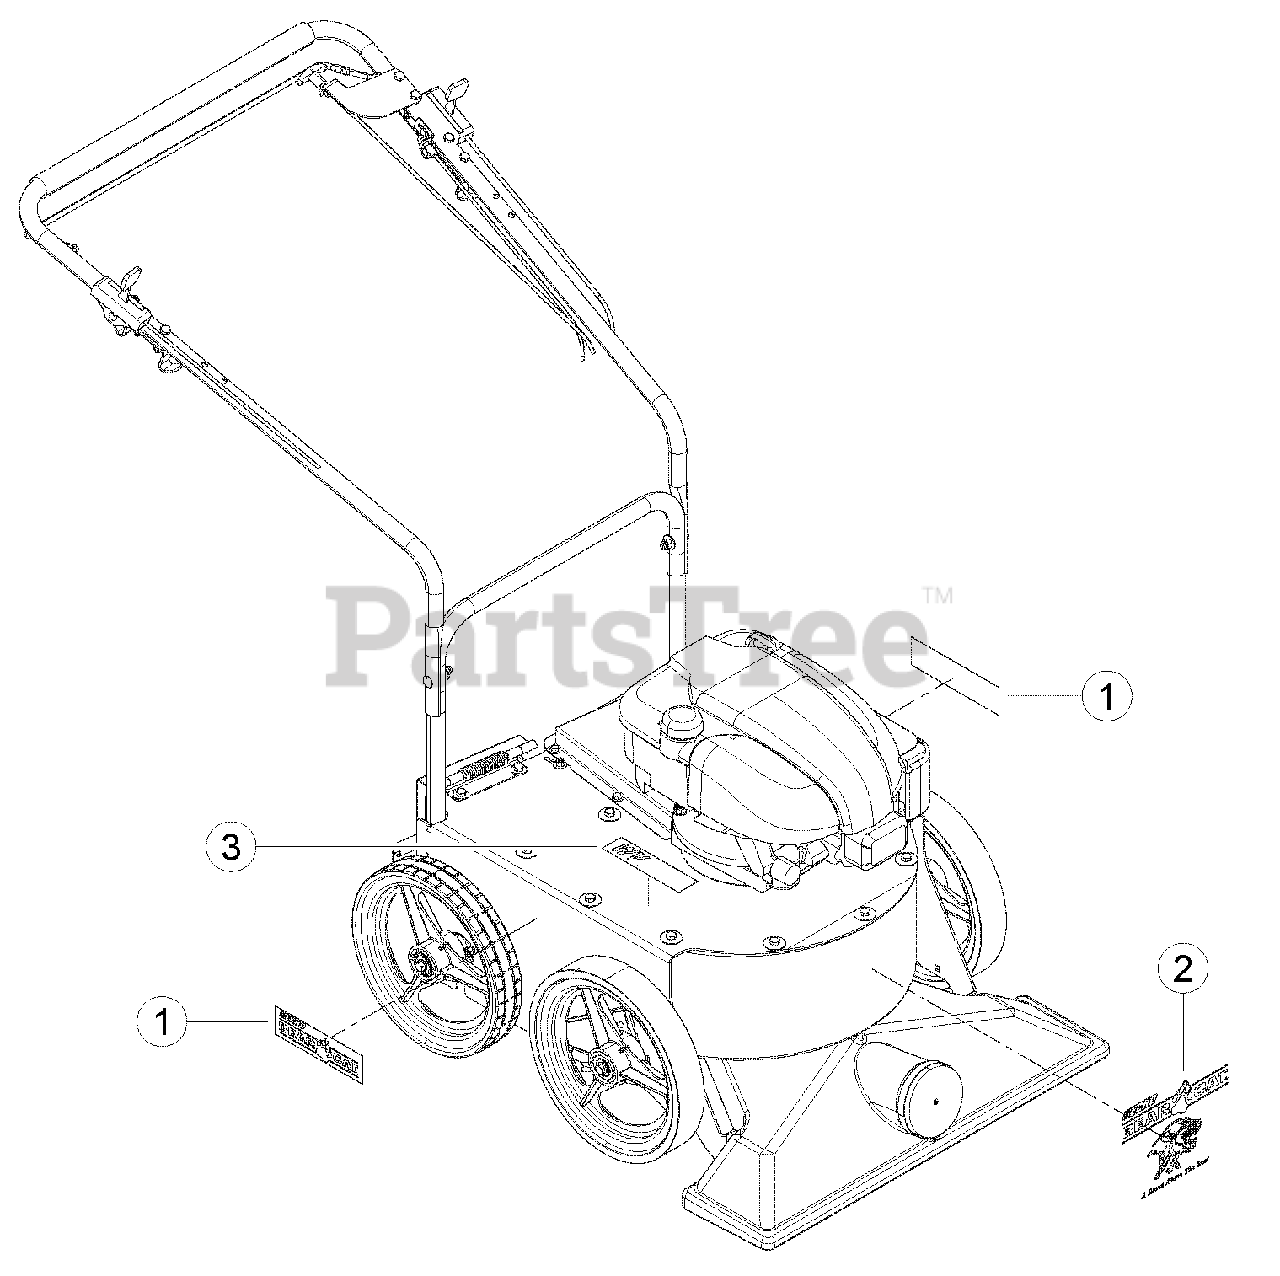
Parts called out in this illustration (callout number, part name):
1	DECAL, ECHO BEARCAT
2	DECAL, ECHO BEARCAT
3	DECAL, MODEL WV160
3	DECAL, MODEL WV160S
3	DECAL, MODEL WV190
3	DECAL, MODEL WV190S
